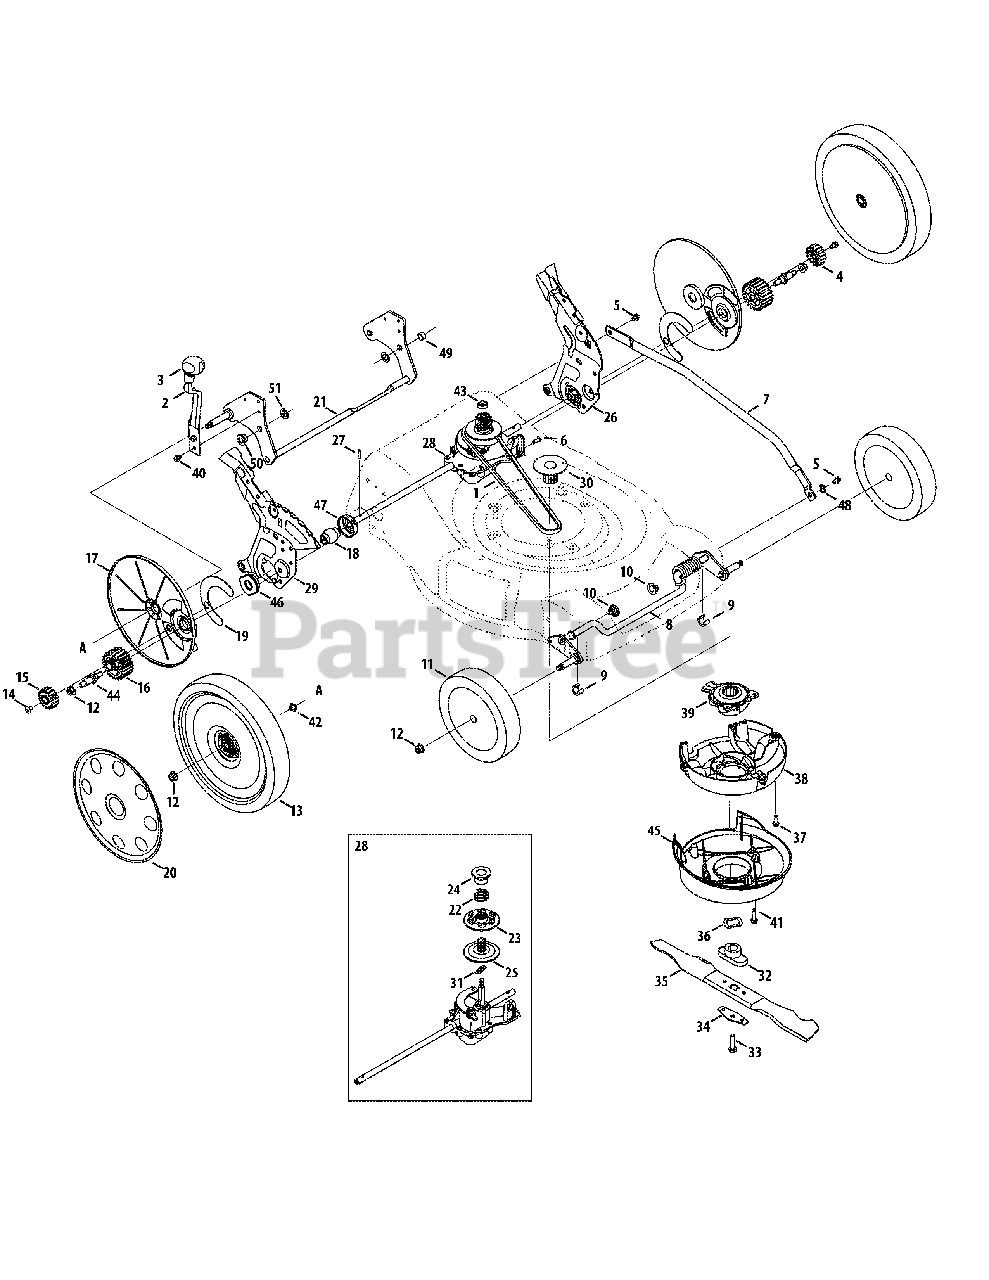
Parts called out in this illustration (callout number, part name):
1	V-Belt
2	Spring Lever
3	Height Adjuster Knob
4	Spur Gear, 16T - LH
5	Shldr. Screw, 1/4-20 x 0.50
6	Screw, #12-16
10	Split Hex Flange Bearing
11	Front Wheel
12	Flange Lock Nut, 3/8-16
13	Rear Wheel
14	Screw, 1/4-20 x .39
15	Spur Gear, 16T - RH
16	Gear, Spur, 23T
17	Wheel Dust Cover
18	Bearing Sleeve
19	Dust Cover Seal Plate
23	Upper Pulley
24	Nut, Shldr.
25	Lower Pulley
26	Handle Bracket Assembly LH
27	Dowel Pin
28	Transmission Assembly
29	Handle Bracket Assembly RH
30	Pulley, Half
31	Extension Spring
32	Blade Adapter
33	Screw, 3/8-24 x 1.50
34	Blade Bell Support
35	21" Mulching Blade
36	Washer, Wave, .88 x 1.31 x .029
37	TT Screw, 1/4-20 x .500
38	Engine
39	Lower Pulley Assembly
40	Screw, TT, 1/4-20 x .375
41	Screw, 1/4-15 x 1.25
42	Washer, Wave, .510 x .750 x .017
43	Spcr., 7/8 x 1.265
44	Shf., .500 Dia. X 2.456
46	Bearing Support
47	Bearing Retainer
48	Washer, Wave, .390 x .625 x .016
49	Spacer, .499 x .685 x .380
50	Spacer, .499 x .860 x .380
51	Washer, Thrust, .375 x .70 x .030
